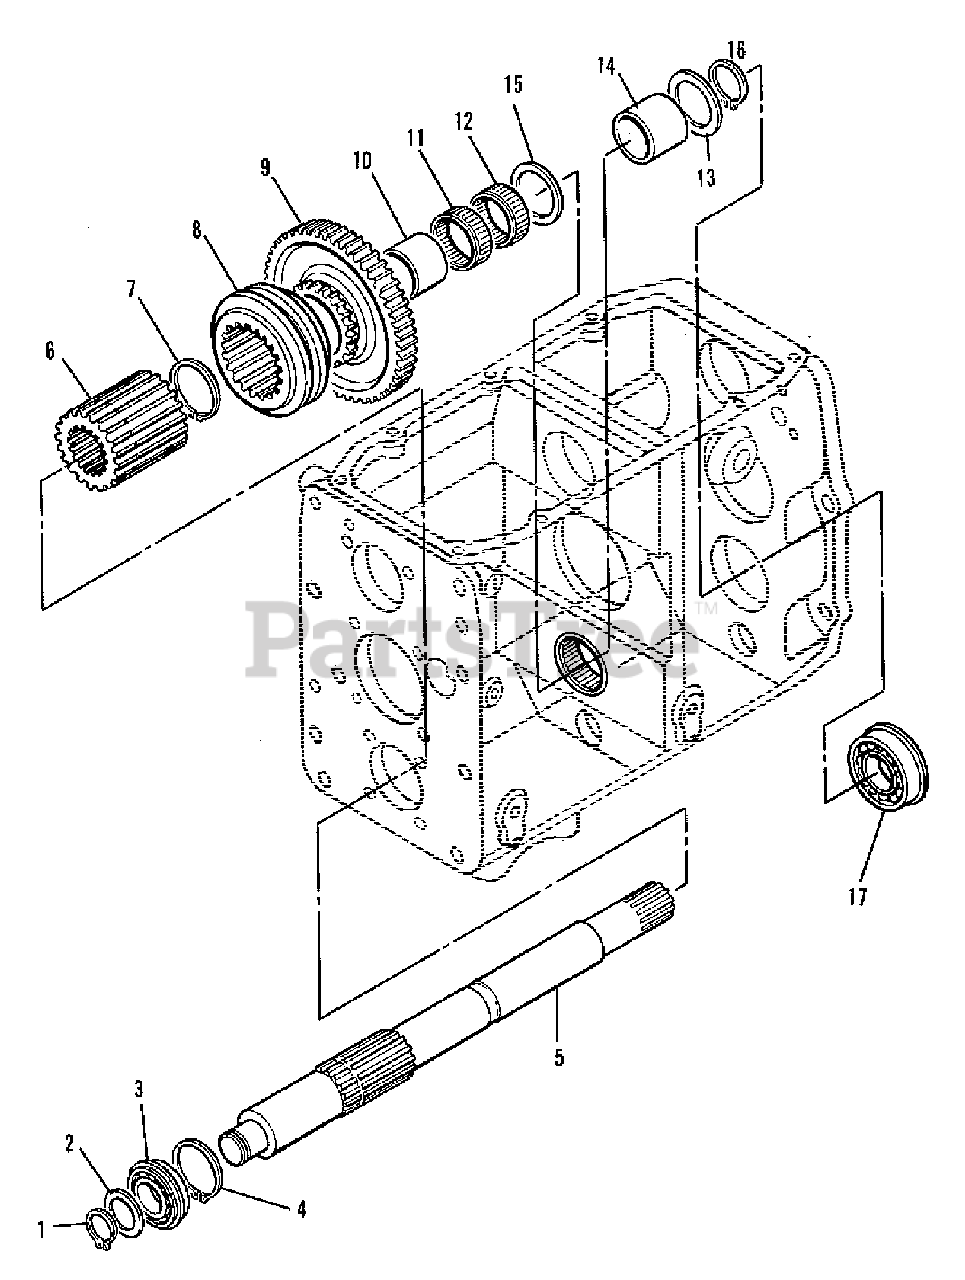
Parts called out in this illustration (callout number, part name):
1	RING, snap-external
2	WASHER, thrust
3	BEARING ASSEMBLY (Incl. SNAP RING)
4	RING, snap-external
5	SHAFT, P.T.O.
6	HUB, P.T.O. sleeve
7	RING, M65, snap-external
8	SLEEVE, P.T.O.
9	GEAR, P.T.O. driven
10	RING, inner-shell type needle bearing
11	BEARING, needle
12	BEARING, needle
13	WASHER, thrust
14	RING, inner-shell type needle bearing
15	WASHER, thrust (3.0)
15	WASHER, thrust (3.3)
15	WASHER, thrust (3.6) (Select)
15	WASHER, thrust (3.9)
16	RING, M35, snap-external
17	BEARING ASSEMBLY (Incl. SNAP RING)
